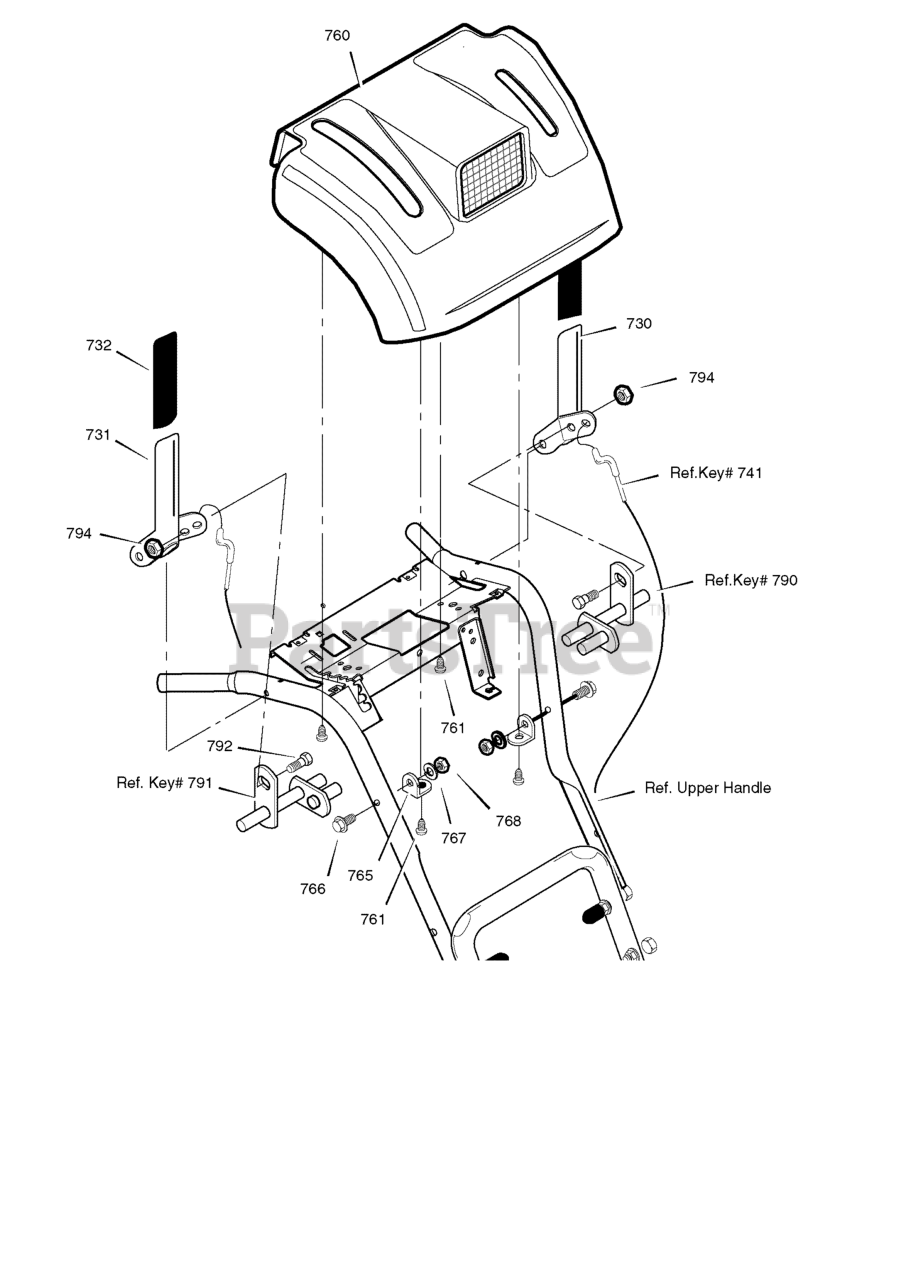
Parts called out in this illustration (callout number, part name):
730	CLUTCH HANDLE LH
731	CLUTCH HANDLE RH
732	GRIP, CLUTCH LEVER
760	PANEL, CONTROL
765	BRACKET, PANEL
766	SCREW, 5/16-18 x 1.75
767	WASHER
768	NUT, 5/16-18
792	BOLT, 1/4-20 X 0.50
794	NUT, 1/4-20
